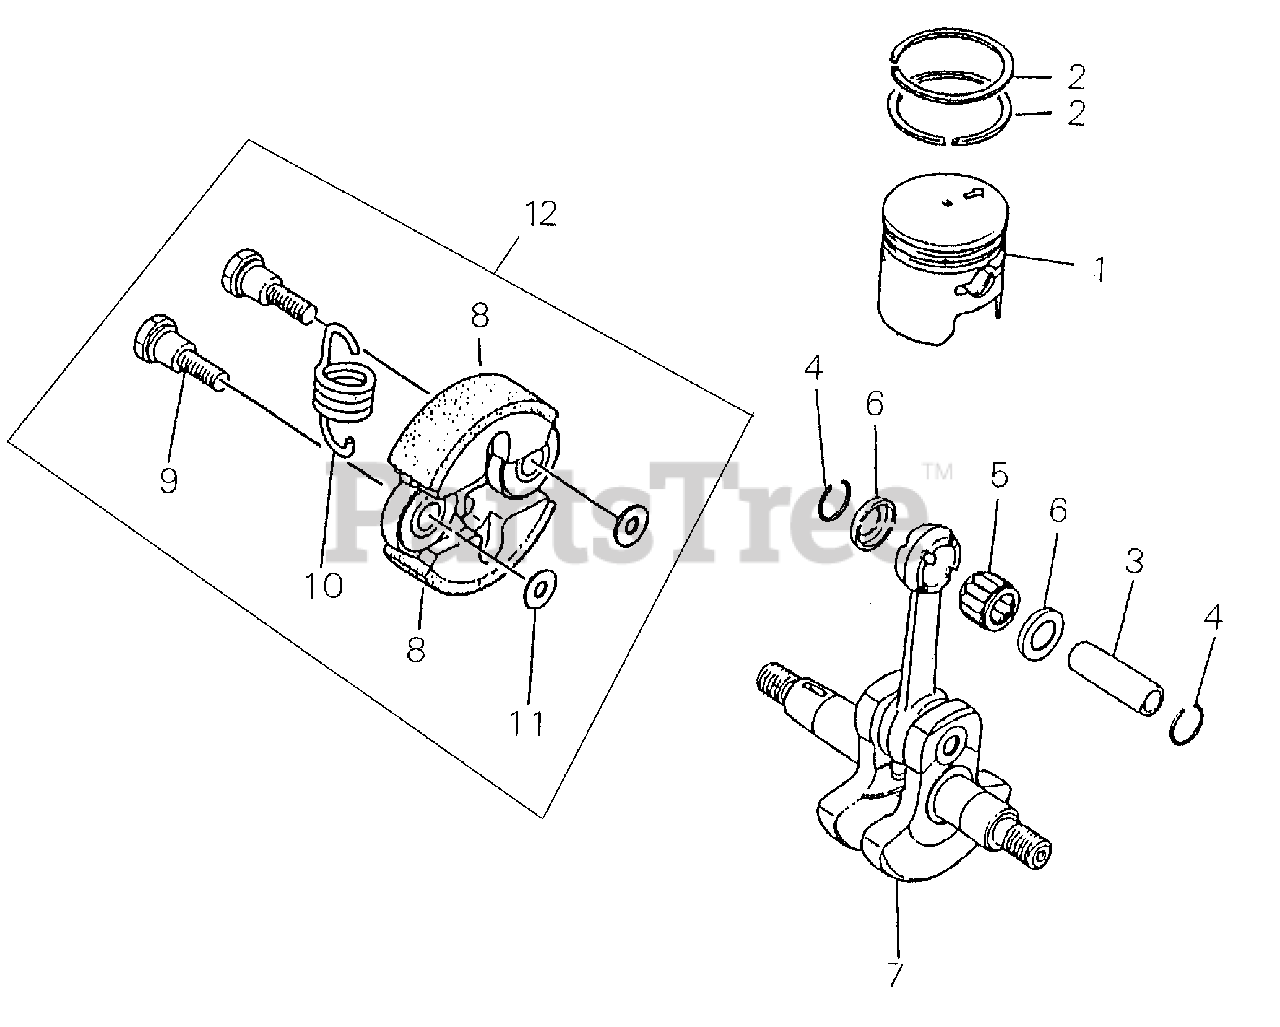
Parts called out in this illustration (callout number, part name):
1	PISTON
2	RING, PISTON
3	PIN, PISTON
4	RING, RETAINING
5	BEARING, NEEDLE
6	SPACER, PISTON
7	CRANKSHAFT ASSY
8	SHOE, CLUTCH
9	BOLT, CLUTCH
10	SPRING, CLUTCH
11	WASHER - 6
12	CLUTCH ASSY
